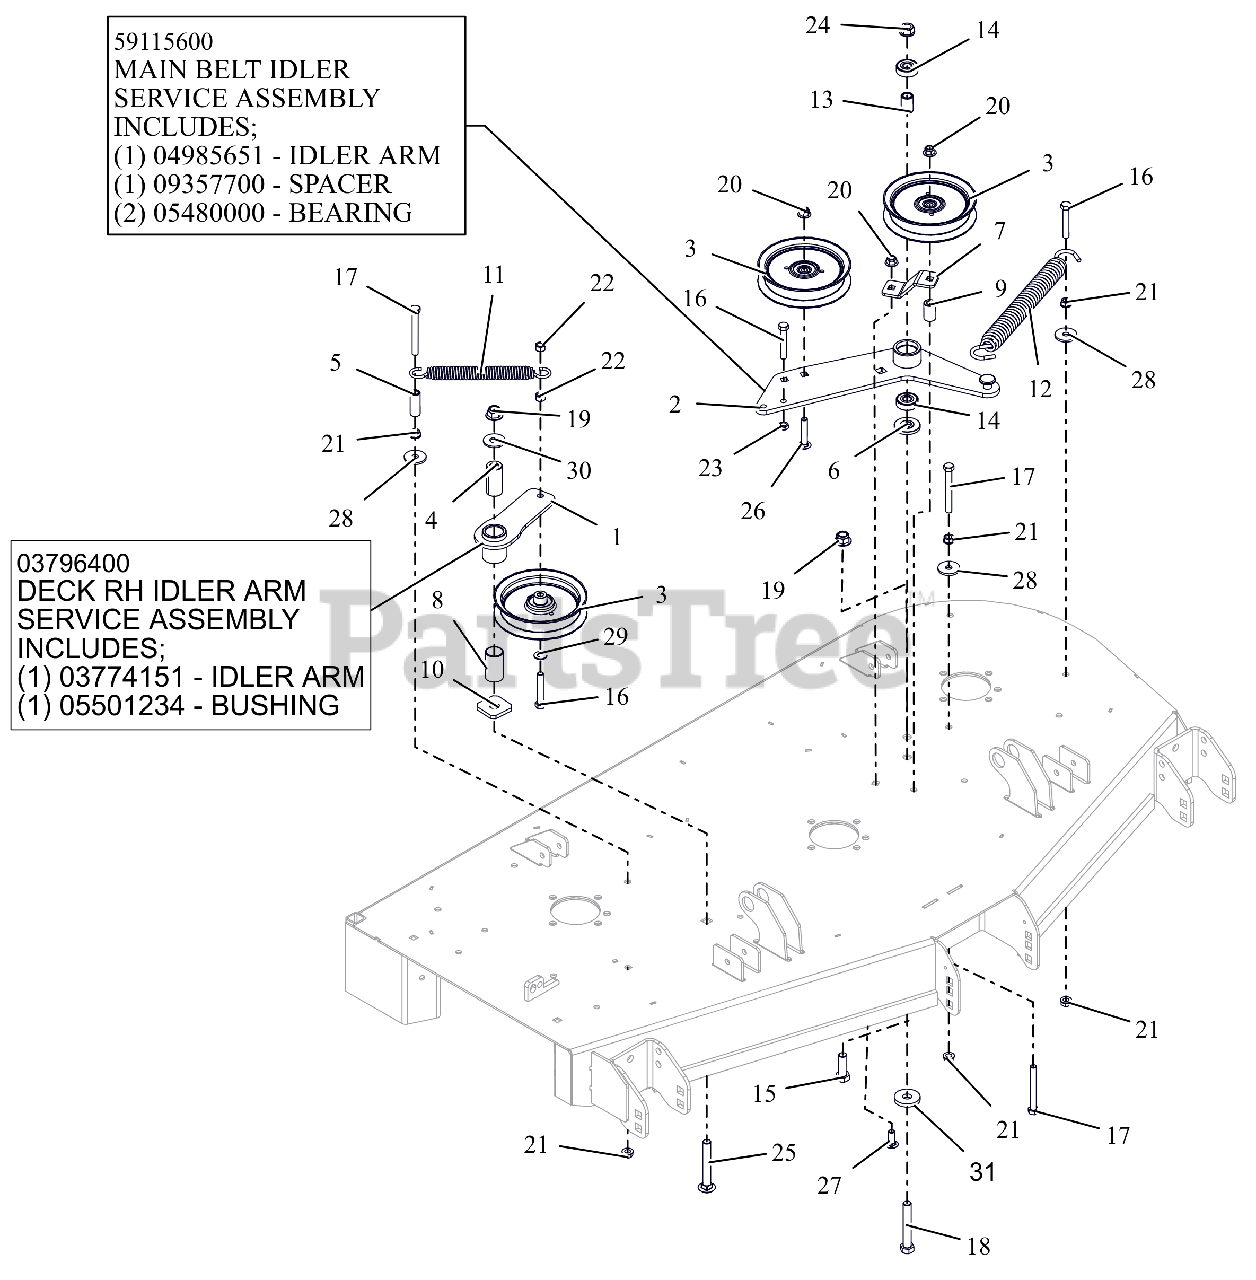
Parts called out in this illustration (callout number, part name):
1	WMT, IDLER ARM - BLACK
1	ASM, IDLER ARM (DECK)
2	DECK PTO IDLER ARM WLDMT - BLK
2	ASSEMBLY, MAIN BELT IDLER
3	IDLER, FLAT 5.00"
4	BSHG, SPCR .502X.997X2.03 PM
5	SPACER, .375IDX.625ODX1.66 PM
6	SPACER, IDLER ARM
7	PTO FIXED IDLER MTG BRKT -RED
8	BSHG, 1.00X1.125X1.937
9	BUSHING, SLV .380X.750X1.190
10	WSHR-FLT .640X1.75X.250
11	SPRING, EXTENSION
12	SPRING, EXTENSION
13	SPACER .510 X .75 X 1.1485
14	BRG-BALL .500X1.38X.437
15	BLT,HEX .50-13X1.50 G5 ZCC
16	BLT,HEX .38-16X2.25 G5 ZCC
17	BLT, HEX .38-16X3.25 G5 ZCC
18	BLT,HEX .50-13X3.25 G5 ZCC
19	NUT,NYL-FLG .50-13 GF ZCC
20	NUT,NYL-FLG .38-16 GF ZCC
21	NUT, SPNLK-FLG .38-16 G5 ZCC
22	NUT-LK-CTR .38-16 ZC120
23	NUT-JAM .375-16 G2 ZCC
24	NUT-LK-CTR-FLG .500-13 GG ZCC
25	BLT, RHSN .50-13X3.50 G5 ZCC
26	BLT,RHSSN.375-16X2.00 G5 ZCC
27	BLT,RHSSN .38-16X1.00 G5 ZCC
28	WSHR,FLT .406X1.375X.135 ZCC
29	WSHR,FLT .406X.812X.065 ZCC
30	WSHR,FLT .563X1.375X.109 ZCC
31	WSHR-FL-STL 0.557X1.625X0.25 ZCC
